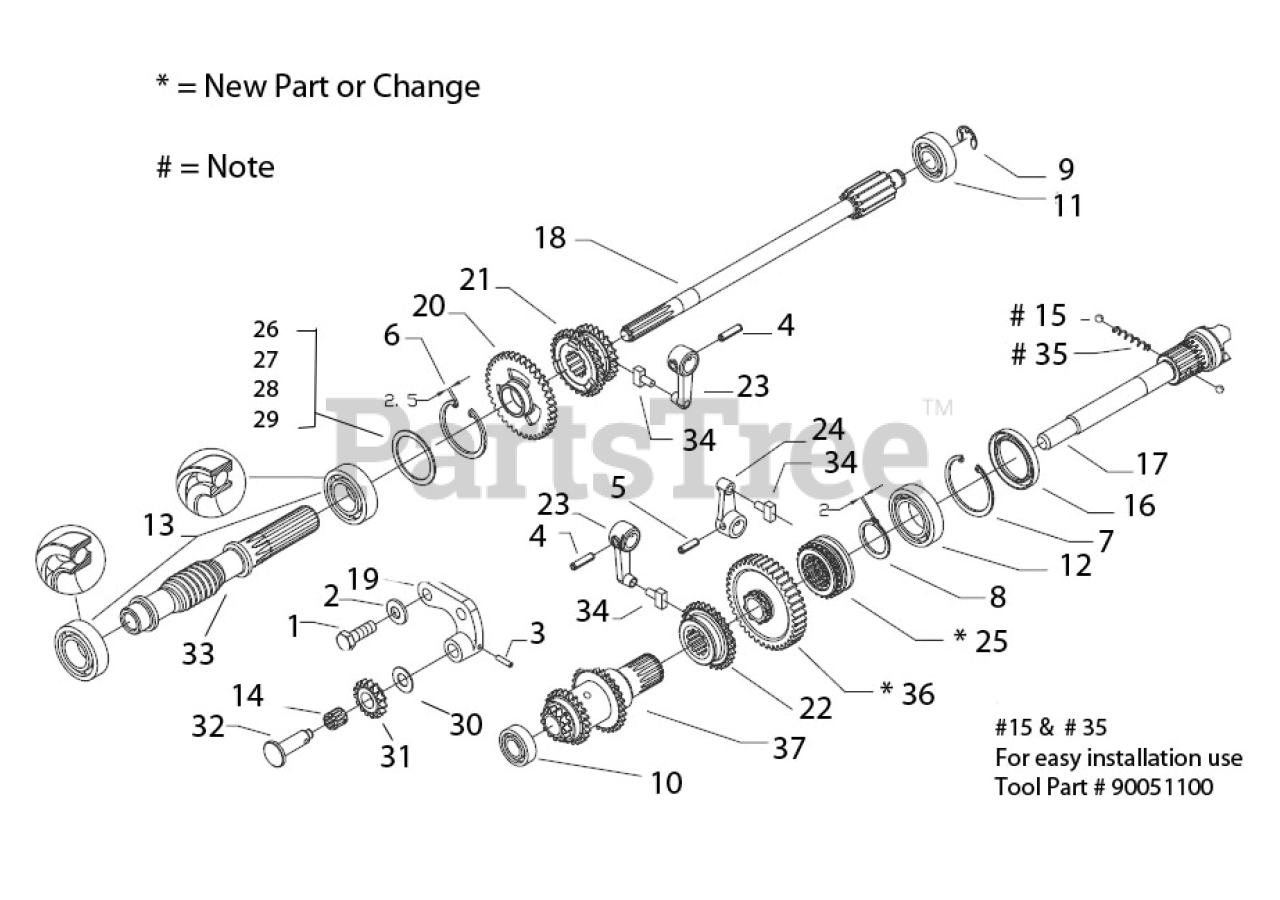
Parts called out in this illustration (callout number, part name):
1	CAP SCREW M10X30
2	WASHER , SUPER M10
3	PIN , SPLIT
4	PIN SPIRAL SPLIT
5	PIN SPIRAL SPLIT
6	SNAP RING D52
7	SNAP RING D55
8	SNAP RING D31
9	RING , SPLIT
10	BEARING 15X35X11
11	BEARING 15X42X13
12	BEARING 30X55X13
13	BEARING 25X52X15
14	BEARING 12X15X10
15	BALL 1/4"
16	OIL SEAL 38X55X7
17	SHAFT , PTO
18	MAIN INPUT SHAFT
19	SUPPORT REVERSE GEAR
20	GEAR , FIRST
21	GEAR , SLIDER
22	SLIDER REVERSER
23	LEVER REVERSER
24	LEVER PTO ENGAEMENT
25	PTO SLIDER
26	SHIM 1.5 MM
27	SHIM 1.6 MM
28	SHIM 1.7 MM
29	SHIM 1.8 MM
30	WASHER
31	REVESER GEAR
32	PIN REVERSE GEAR
33	WORM GEAR
35	SPRING FOR PTO BALLS
36	PTO GEAR
36	PTO GEAR KIT CONSISTS OF 25 & 36
37	GEAR CLUSTER
